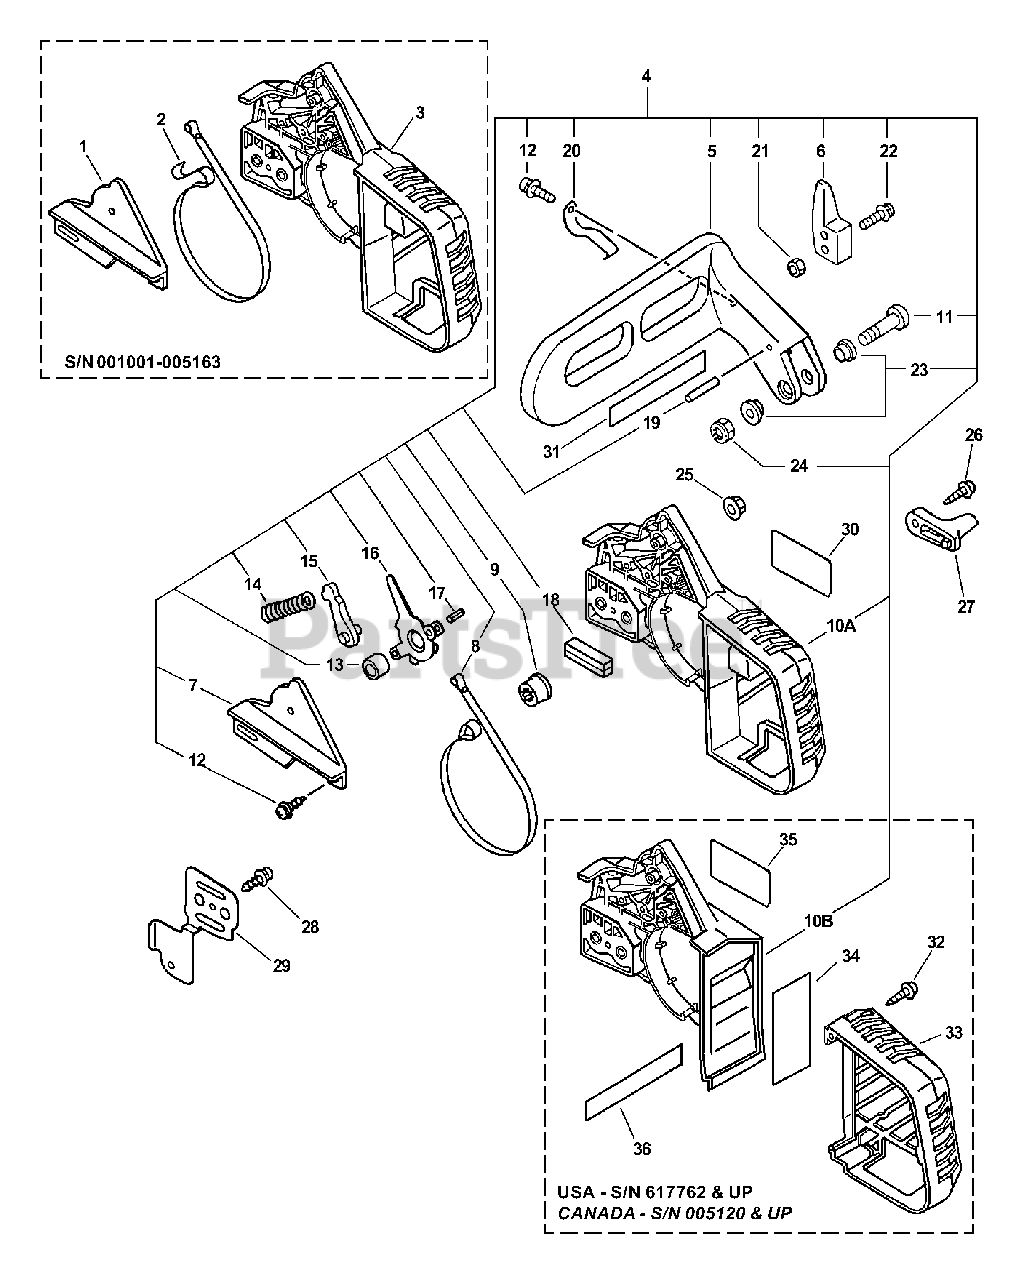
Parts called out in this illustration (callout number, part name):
1	COVER, BRAKE
2	BAND, BRAKE
3	GUARD, SPROCKET
4	CHAIN BRAKE ASSY
5	LEVER, BRAKE
6	WEIGHT, BRAKE
7	COVER, BRAKE
8	BAND, BRAKE
9	ADJUSTER, BRAKE
10A	GUARD, SPROCKET
10B	GUARD, SPROCKET
11	SCREW 5×30
11	SCREW 5×32
12	SCREW 4×10
13	SPACER 8×12×9
14	SPRING, COMPRESSION
15	STOPPER, BRAKE
16	LEVER, BRAKE
17	PIN, SPRING 4×8.8
18	SEAL, BRAKE
19	ROLLER 4×23.8
20	SPRING, FLAT
21	NUT M4
22	SCREW 4×22
23	COLLAR 5.3×10×13×L5
24	NUT, LOCK M5
25	NUT, FLANGE M6
26	SCREW, TAPPING 5×20
27	CHAIN CATCHER
28	SCREW 4×10
29	PLATE, GUIDE
30	LABEL, CS-3450
31	LABEL, BAR & CHAIN
32	SCREW, TAPPING 5×20
33	COVER, EXHAUST
34	SHIELD, HEAT 35×60×0.10
35	LABEL, MODEL
36	LABEL, BAR & CHAIN
